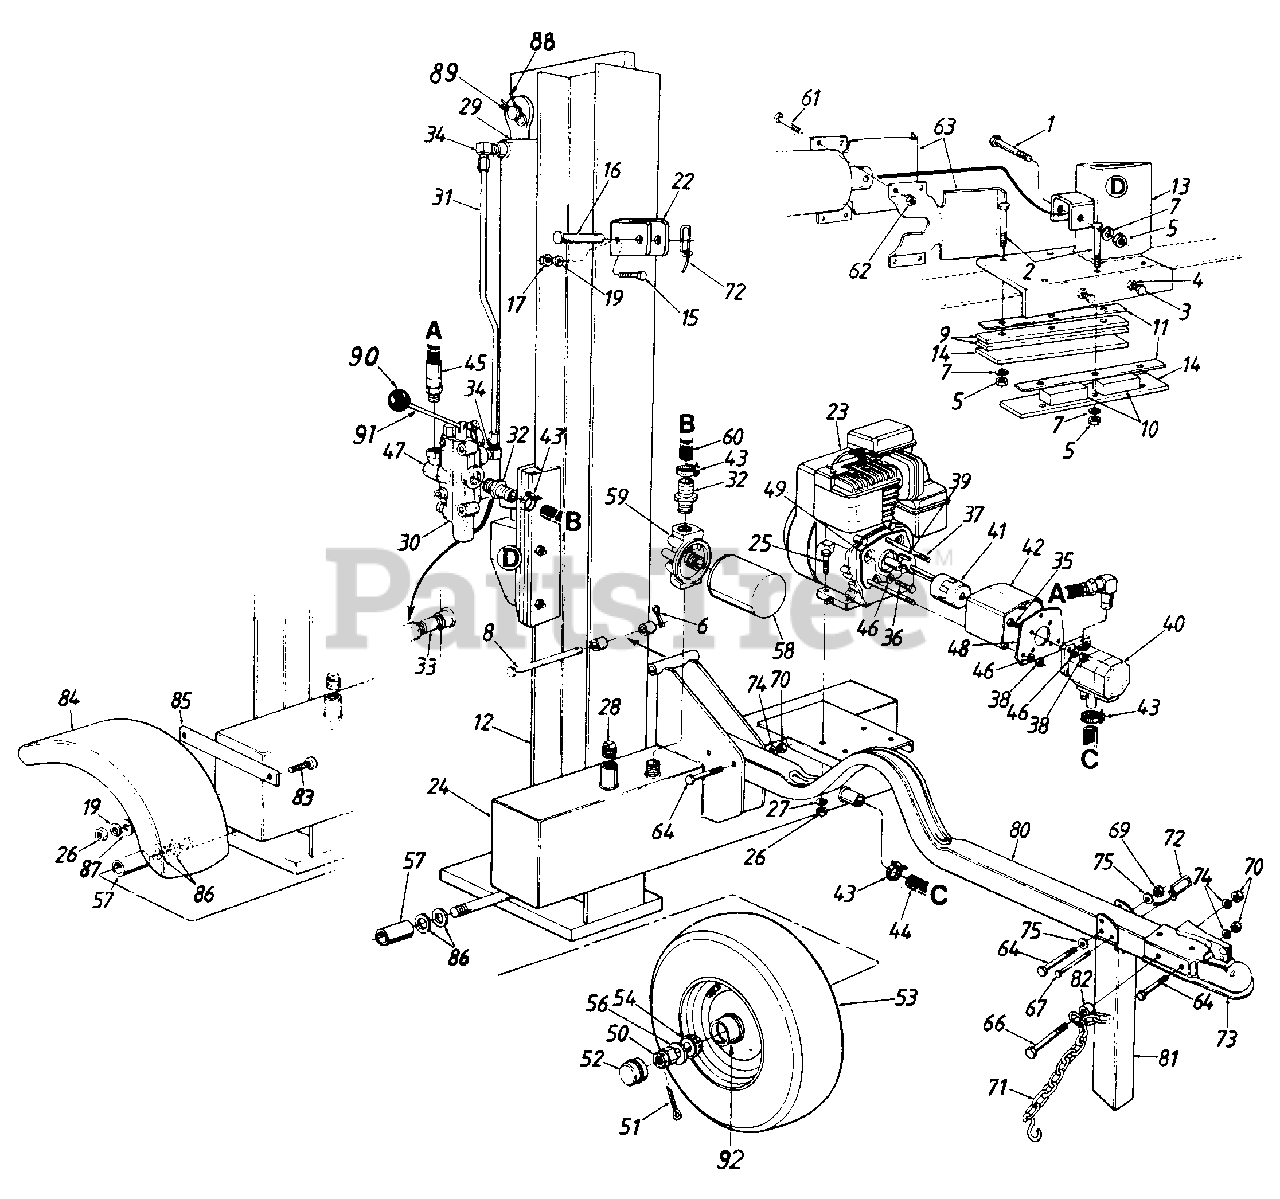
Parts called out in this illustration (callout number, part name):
1	Hex Bolt 1/2-20 x 3" Lg. (Grade 8)
2	Hex Bolt 1/2-20 x 2.75" Lg. (Grade 8)
3	Hex Bolt 7/16-20 x 1.25" Lg.
4	Hex Jam Nut 7/16-20 Thd.
5	Hex Nut 1/2-20 Thd. (Grade 8)
6	Coter Pin 1/8 Dia.
7	L-Wash. 1/2" I.D.*
8	Hinge Pin 1/2" Dia.
9	Fixed Side Gib
10	Adjustable Gib
11	Adjustable Gib Shim
12	Beam Ass'y.
13	Wedge Ass'y.
14	Wedge Back Plate
15	Hex Bolt 5/16-24 x 1.25"
16	Clevis Pin
17	Hex Nut 5/16-24 Thd.(Grade 5)
19	L-Wash. 5/16" I.D.*
22	Pivot Latch Brkt.
23	Engine
24	Tank Ass'y. Complete
25	Hex Bolt 5/16-24 x 1.75"
26	Hex Nut 5/16-24 Thd.*
27	L.Wash. 5/16" I.D.*
28	Vent Plug
29	Hydraulic Cylinder
30	Control Valve
31	Metal Pressure Tube
32	3/4" Hose Barb
33	Pipe Nipple
34	Elbow
35	Hex Bolt 5/16-24 x 1.0" Lg.*
36	Hex Bolt 5/16-24 x .62" Lg.*
37	Hex Bolt 5/16-24 x 4" Lg.
38	Hex Nut 5/16-24 Thd.*
39	Sq. Key 3/16" x .75"
41	Flexible Coupling
42	Coupling Shield
43	Adjustable Hose Clamp
44	Suction Hose-20"
45	Pressure Hose
46	L-Wash. 5/16" I.D.*
47	90ø Swivel
50	Hex Sloted Nut 3/4-16 Thd.
51	Coter Pin 5/32" Dia.
52	Hub Cap
54	Roller Bearing w/Race
56	Fl.Wash. .76" I.D. x 1.5" O.D.
57	Spacer 1.56" Lg.
58	Filter Element
59	Filter Head
60	Return Hose- 30"
61	Hex Bolt 3/8-16 x 2" 4.(Grade 5)
62	Hex L-Nut 3/8-16 Thd.
63	Stripper Half
64	Hex Bolt 3/8-16x 3" 4. (Grade 8)
66	Hex Bolt 3/8-16 x 3.25" 4. (Grade 8)
67	Clevis Pin 5/16" Dia.
69	Hex L-Nut 3/8-16 Thd.
70	Hex Nut 3/8-16 Thd.*
71	Tow Hitch Chain
72	Spring Pin
73	Hitch Coupler
74	L-Wash. 3/8" I.D.*
75	Fl.Wash. .406" I.D. x .75" O.D.
80	Tongue
83	Hex Bolt 5/16-24 x 3/4" Lg. (Grade 5)
84	Fender
85	Fender Support
86	Fl.Wash. .78" I.D. x 2.0" O.D.
87	Fl.Wash. .344" I.D. x .88"
88	Hairpin l" Dia.
89	Clevis Pin l" Dia. x 1.88" Lg.
90	Ball Knob
91	Valve Control Rod
92	Seal 1" I.D.
